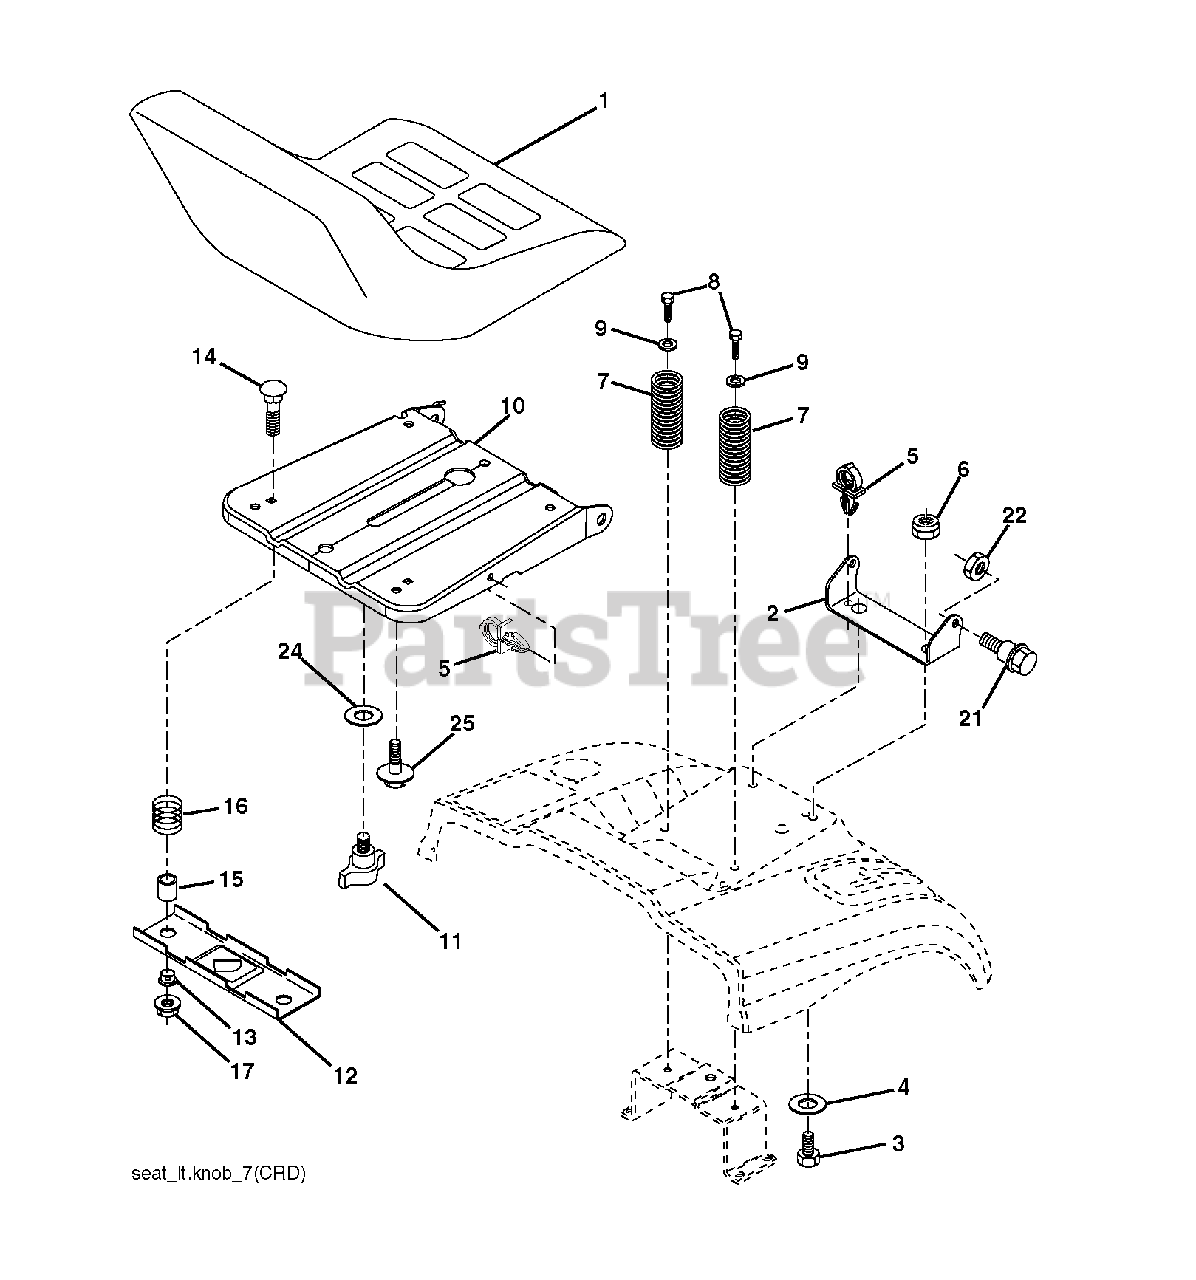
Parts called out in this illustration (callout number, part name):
1	SEAT.XG150.BLK.KB/SLD.NO-LOGO
2	SEAT PIVOT BRKT
4	WASHER PM
5	PUSH CLIP
6	NUT
7	SPRING COMPRESSION
8	SCREW 3/8-16X1
9	WASHER
10	PAN.ASM.SEAT.1SLOT
11	KNOB.SEAT.ADJ.WINGNUT
12	BRKT.MNTNG.SWITCH.SEAT
14	BOLT.ROUND.HEAD.SQUARE.NECK
15	SPACER SPLIT
16	SPRING COMPRESSED
17	NUT T
21	BOLT.SHOULDER.5/16-18
22	NUT.71038.31-18.HEX.NYLOCK
25	BOLT,SHOULD
